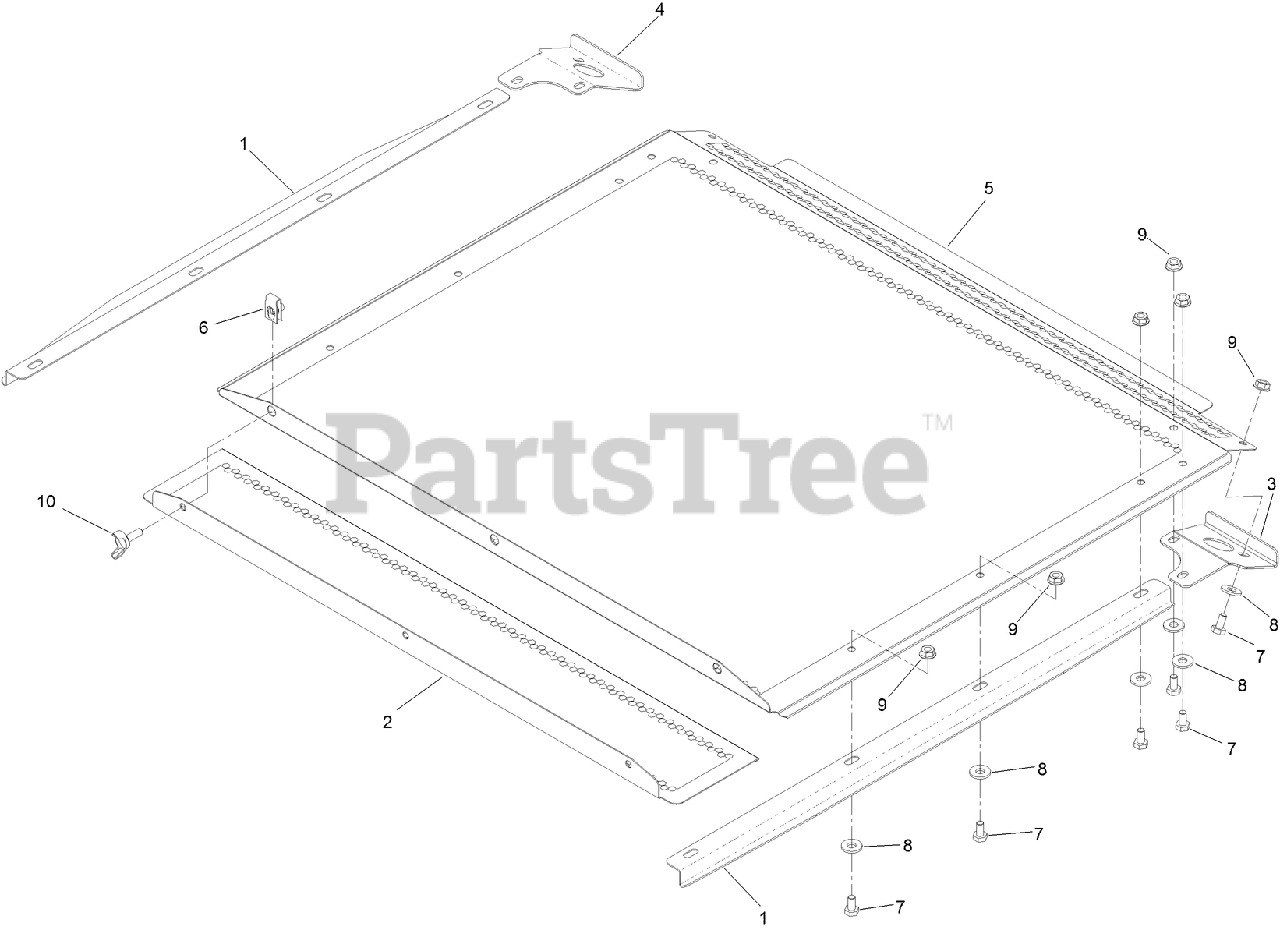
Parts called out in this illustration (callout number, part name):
1	GUIDE-SCREEN
2	PANEL-SCREEN, REMOVABLE
3	HANDLE-SCREEN, LH
4	HANDLE-SCREEN, RH
5	PANEL-SCREEN, HOPPER
7	SCREW-HH
8	WASHER-FLAT
9	NUT-HF
10	SCREW-WING
